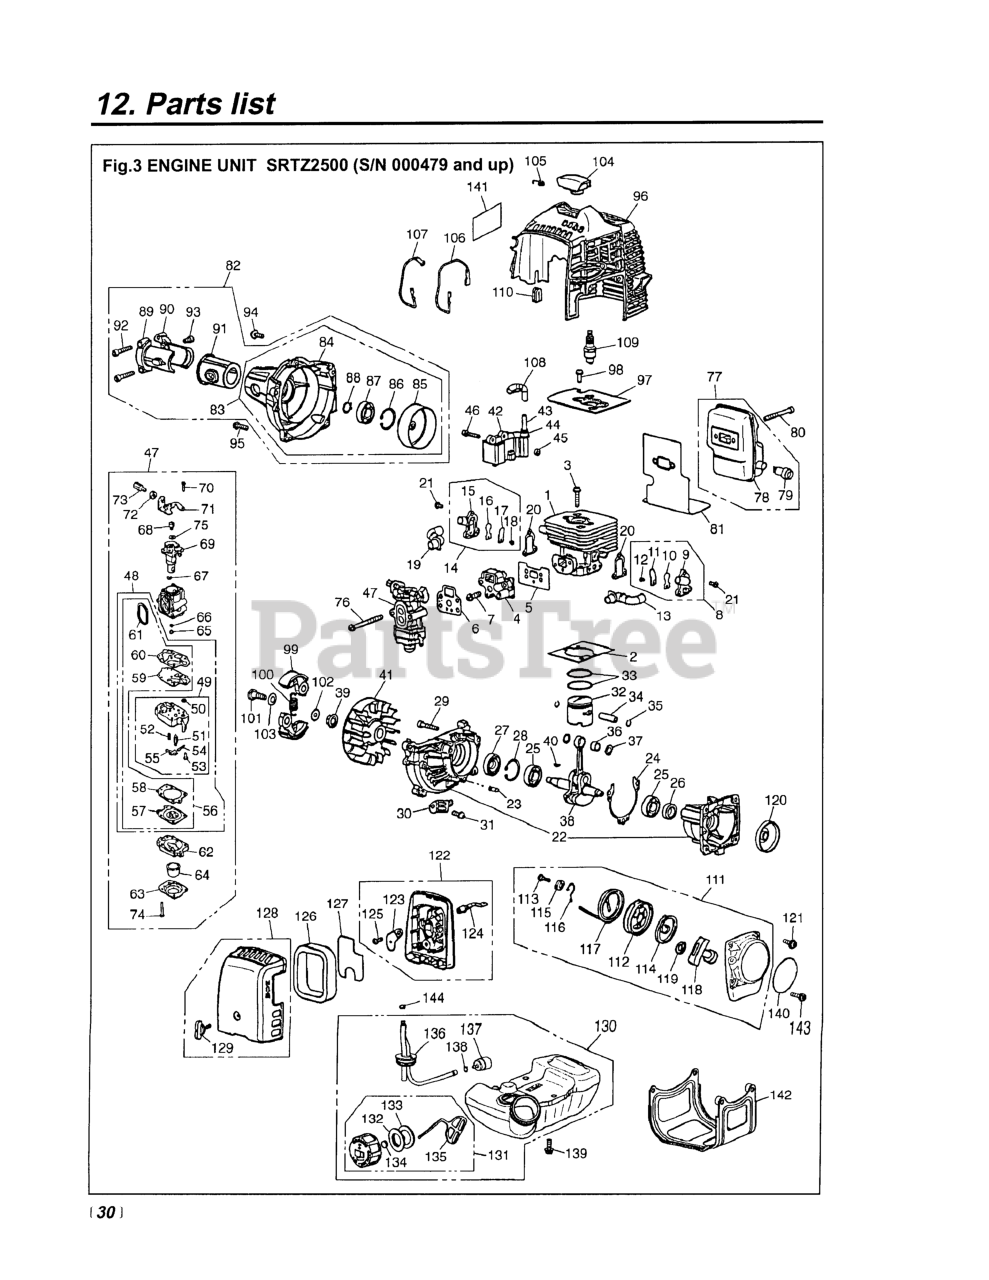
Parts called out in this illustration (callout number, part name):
1	CYLINDER (RPLS -12110)
2	GASKET, BASE
3	BOLT, M5 X 22
4	INSULATOR (RPLS. -13160/13161)
5	GASKET, INSULATOR
6	GASKET, CARBURETOR
7	SCREW, M5X20 (RPLS.1400-75510)
9	CASE VALVE
10	VALVE, REED
11	STOPPER
12	SCREW, M3 x 8
13	PIPE, AIR
16	VALVE, REED
17	STOPPER
18	SCREW, M3 x 8
19	PIPE, AIR (F)
20	GASKET, VALVE
21	SCREW
22	CRANKCASE-C
23	PIN
24	GASKET
25	BEARING
26	SEAL
27	SEAL, OIL (RPLS 1140-21220)
28	RING, SNAP, M28 x 1.2
29	BOLT, M5 X 30
31	SCREW, M5 X 10
32	PISTON
33	RING, PISTON
34	PIN, PISTON
35	RING, SNAP (RPLS 1101-41320)
36	BEARING (RPLS 1140-41330)
37	WASHER
38	CRANKSHAFT COMPLETE
40	KEY
41	ROTOR
42	COIL-A
43	CORD
44	CAP
45	SPACER (RPLS -71260)
46	BOLT, M4 x 22
49	PUMP BODY ASSEMBLY
50	SCREEN
51	VALVE, INLET
53	SCREW
54	PIN
55	LEVER
57	DIAPHRAGM
58	GASKET, DIAPHRAGM
59	DIAPHRAGM, PUMP
60	GASKET, PUMP
61	RING
62	BODY, PURGE
63	COVER, PUMP
64	PUMP, PRIMING
65	JET (USE -81251)
66	RING, O
67	RING
68	SWIVEL
69	VALVE ASSY
70	SCREW
72	NUT, CABLE ADJUSTER
73	SCREW, CABLE ADJUSTER
74	SCREW
75	WASHER
76	SCREW, M5 x 60
77	MUFFLER ASSEMBLY
78	MUFFLER (REPLACES -15110)
79	ARRESTER
80	BOLT, M5 x 50
81	GASKET (RPLS T1501-15210)
82	COVER-A (USE -31002)
83	COVER-C (USE -31102)
84	COVER, FAN (USE -31111)
86	RING, SNAP, M28 x 1.2
88	RING, SNAP (RPLS 3130-13270)
89	BRACKET (A) (RPLS -31210)
90	BRACKET (B) (REPLACES -31220)
91	CUSHION
92	BOLT, M5 X 30
93	BOLT (USE 3310-31720)
94	SCREW
95	SCREW, M5X20 (RPLS.1400-75510)
96	COVER, ENGINE (RPLS -32110)
97	PLATE, CYLINDER
98	SCREW, M5 X 10
99	SHOE
100	SPRING
101	BOLT
102	WASHER, FLAT (USE 182303)
103	WASHER (RPLS -51241)
105	SPRING
106	CORD (BLACK)
107	CORD, EARTH (RED)
108	TUBE
110	GROMMET
111	RECOIL ASSEMBLY
112	REEL
113	SCREW
114	SPRING, SPIRAL
115	COLLAR
116	ARM
117	ROPE (REPLACES 4500-75160)
118	KNOB (RPLS -75420)
119	PLATE, STOPPER
120	PULLEY
121	SCREW
122	BODY ASSEMBLY
123	PLATE, CHOKE
124	LEVER, CHOKE
125	SCREW (REPLACES 50030272)
126	ELEMENT
127	SCREEN
128	COVER ASSEMBLY
129	KNOB (RPLS -82220)
131	CAP ASSY (RPLS -85201)
132	HOLDER (REPLACES -85230)
133	PACKING
134	FILTER
135	STOPPER
136	PIPE COMPLETE
137	FILTER (RPLS 1850-85300)
138	CLIP (REPLACES 2841-31280)
139	SCREW
140	LABEL, RECOIL
141	LABEL, COVER
142	GUARD (RPLS 4810-31911)
143	SCREW, M5 x 25
144	CLIP
